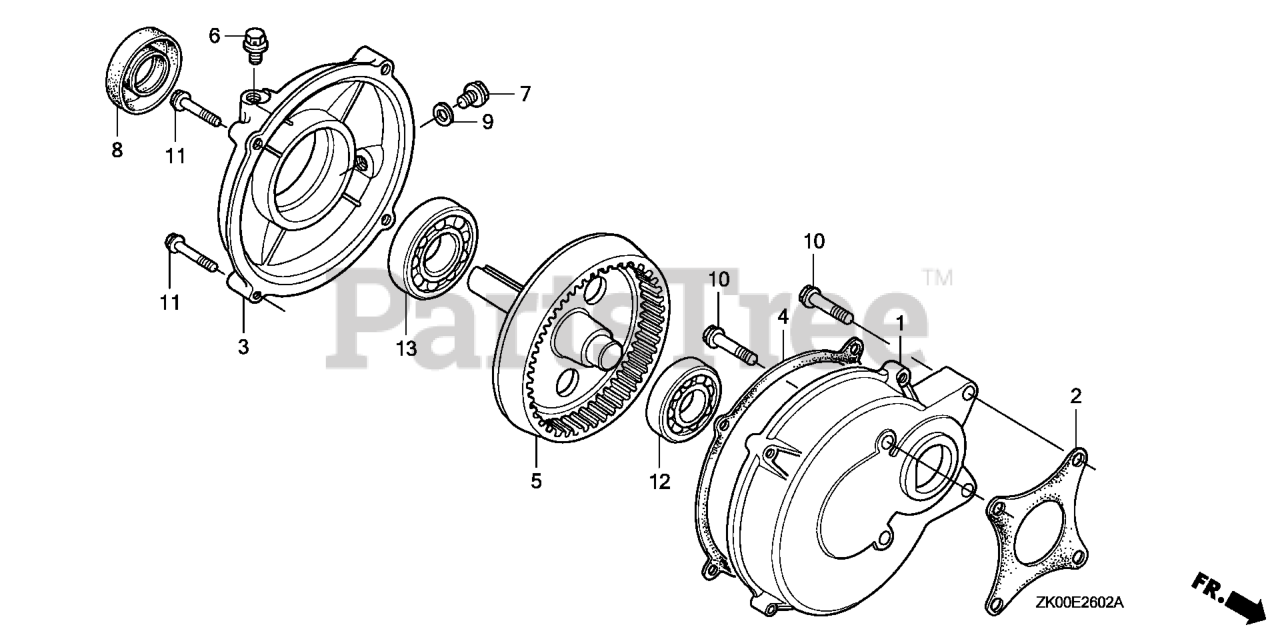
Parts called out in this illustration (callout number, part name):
1	CASE, REDUCTION
2	GASKET, REDUCTION CASE
3	COVER, REDUCTION
4	GASKET, REDUCTION COVER
5	SHAFT, P.T.O.
6	BOLT, BREATHING
7	BOLT, DRAIN PLUG
8	OIL SEAL (25X41X6)
9	WASHER, DRAIN PLUG (12MM)
10	BOLT, FLANGE (8X32)
11	BOLT, FLANGE (8X35)
12	BEARING, RADIAL BALL (6204)
13	BEARING, RADIAL BALL (6305)
